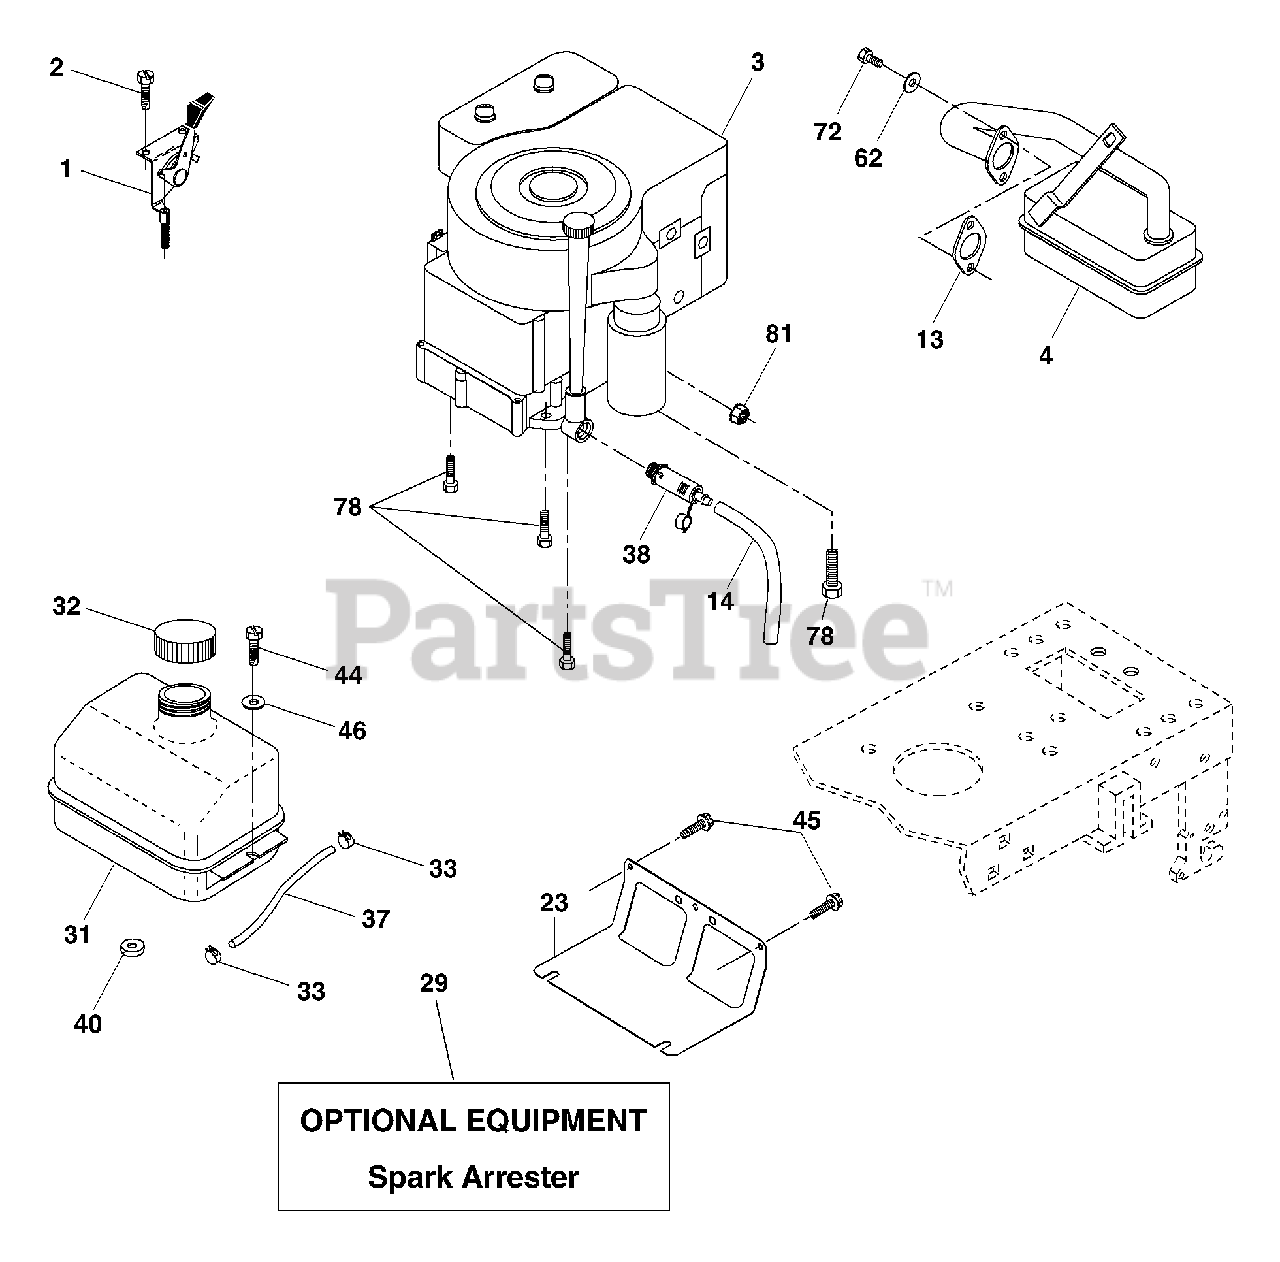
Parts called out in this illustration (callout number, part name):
1	Control Throttle /Choke Flag
2	Screw Hex Thd Cut 1/4-20 x 1/2
4	Muffl er Exhaust B&S Lt
13	Gasket 1 313 Id Tin Plated
14	Tube Drain Oil Easy
23	Shield Browning/Debris Guard
29	Arrestor Spark
31	Tank Fuel 1 25 Fr
32	Cap Asm Fuel Top
33	Clamp Hose Blk
37	Line Fuel 20"
38	Plug Drain Oil Easy
40	Bushing Snap Nyl Blk Fuel Line
44	Screw Hexwsh Thdrol 1/4-20 x 3/4
45	Screw Hex Wsh Thdrol 3/8-16
46	Washer 9/32 X 7/8 X 16 Ga.
62	Washer Split
72	Screw Socket Head 5/16-18 x .75
78	Screw Thdrol 3/8-16 x 1-1/4
81	Nut Keps Hex 1/4-20 unc
